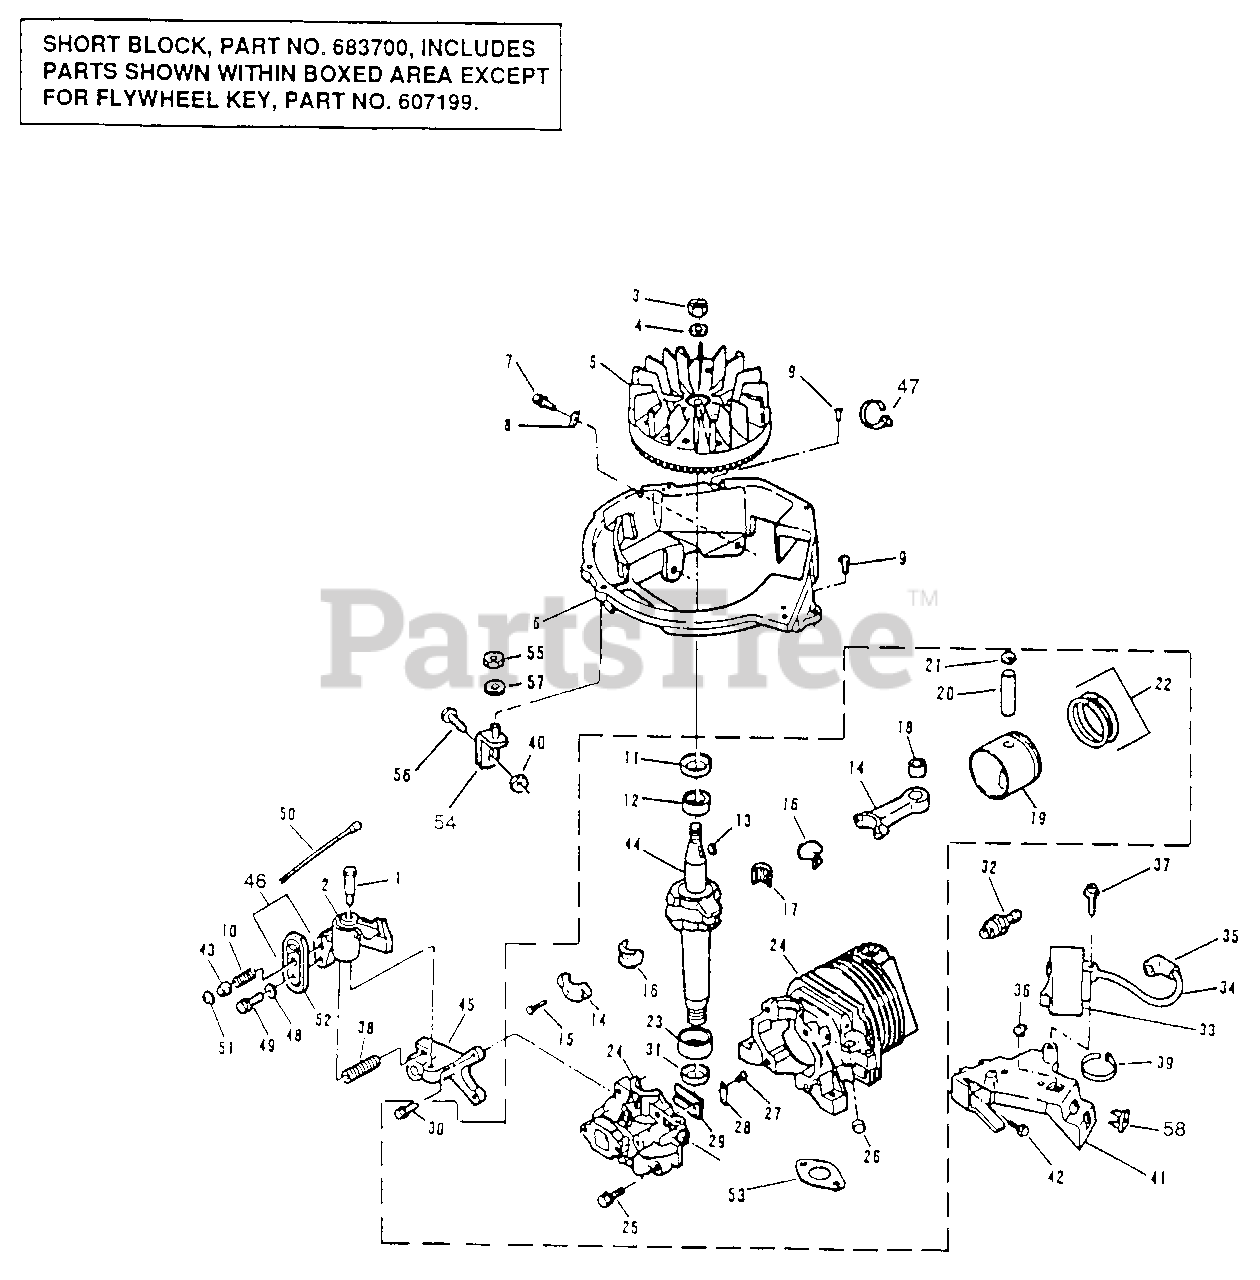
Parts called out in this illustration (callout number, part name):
1	Bolt-Shoulder
2	Brake Assembly
3	Nut-Flywheel
4	Lockwasher
5	Flywheel Assembly
6	Base-Shroud
7	Screw
8	Clip-"J"
9	Screw
10	Spring-Cable Return
11	Oil Seal-Upper
12	Bearing-Main-Upper
13	Key-Flywheel
14	Connecting Rod Assy (Inc. 15-18)
15	Screw-Cap
16	Liner Split
17	Needle Bearing Set
18	Bearing Assembly
19	Piston & Ring Set (Inc. 20-22)
20	Wrist Pin
21	Retaining Ring
22	Ring Set
23	Bearing-Main-Lower
24	Cylinder & Crankcase Cover Asy. (Inc. 25-30)
25	Screw-Cover to Crankcase
26	Plug
27	Screw-Reed to C'case Cover
28	Plate-Reed Hold Down
29	Reed
30	Screw-Brake Mounting Bkt.
31	Oil Seal-Lower
32	Spark Plug
33	C.D. Ignition Module & Lead Asy (Inc. 34-35)
34	High Tension Lead & Cvr (Inc. 35)
35	Cover & Terminal Assembly
36	Grommet
37	Screw-C.D. Mounting
38	Spring-Brake
39	Tie Strap
40	Nut
41	Bracket-C.D. Mounting
42	Screw
43	Actuator-Brake Lever
44	Crankshaft
45	Bracket-Brake
46	Switch Assembly (Inc. 47-52)
47	Tie Strap
48	Washer
49	Screw
50	Lead Assembly
51	Retainer
52	Case Assembly-Only
53	Exhaust Gasket
54	Brace Assembly
55	Nut
56	Bolt
57	Washer
58	Speed Nut
